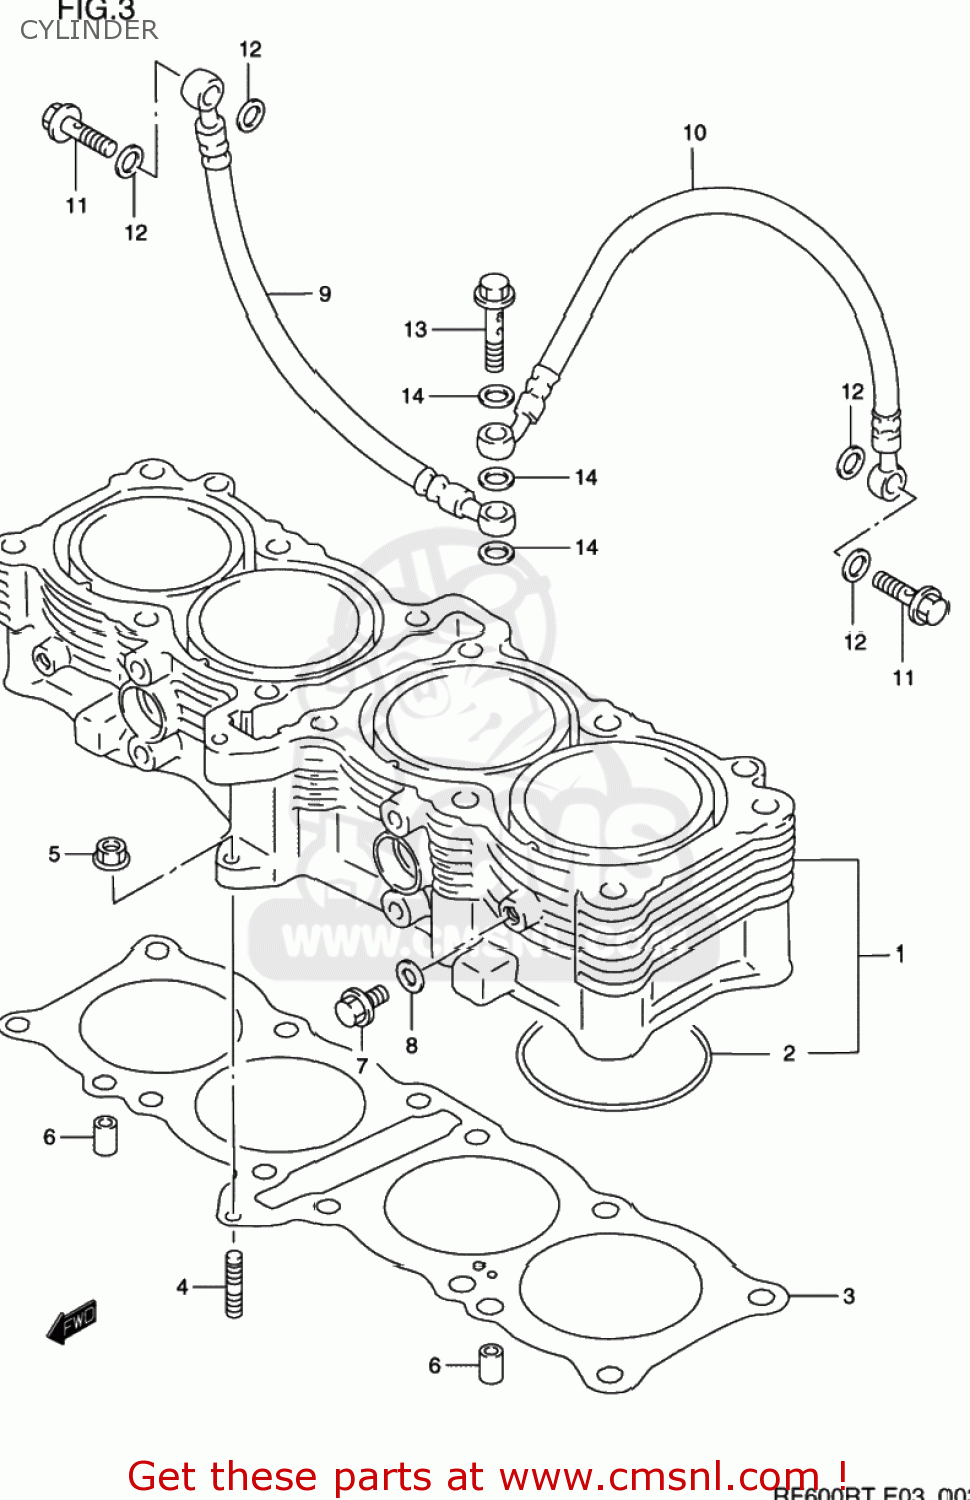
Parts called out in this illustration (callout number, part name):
1	CYLINDER
2	O RING(D:2.6,ID:69.6)
3	GASKET,CYLINDER
4	STUD,M6X1X32
5	NUT
6	PIN
7	BOLT,DRAIN
8	GASKET 8.2X14X1 (NAS)
9	HOSE,CYLINDER HEAD OIL,R
10	HOSE,CYLINDER HEAD OIL,L
11	BOLT,OIL PIPE UNION,NO
12	GASKET(8.2X14X1) (NAS)
13	BOLT,OIL PIPE UNION,NO
14	WASHER(10X15X1.5)
